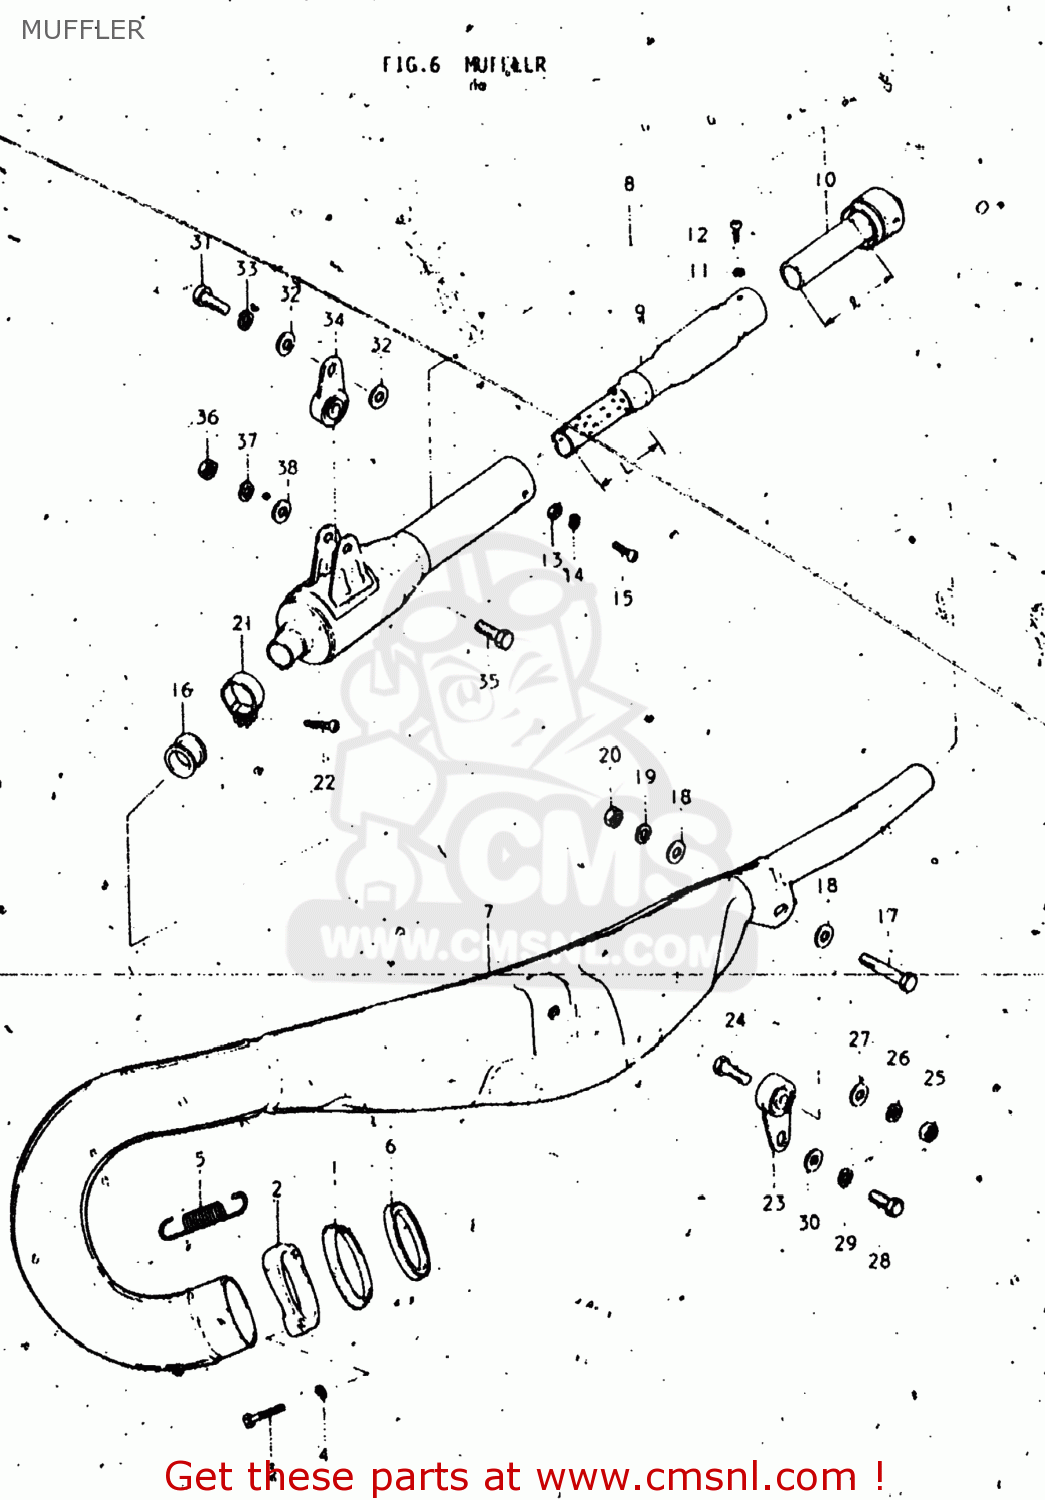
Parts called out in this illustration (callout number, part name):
1	GASKET,EXHAUST PIPE (NAS)
2	CLAMP,EXHAUST PIPE
3	BOLT
4	LOCK WASHER
5	SPRING
6	GASKET,EXHAUST PIPE
7	BODY,MUFFLER
8	MUFFLER ASSEMBLY
9	ARRESTER,SPARK
10	TUBE,MUFFLER CLEAN OUT
11	LOCK WASHER
12	SCREW
13	WASHER
14	LOCK WASHER
15	SCREW(6X8)
16	CONNECTOR,MUFFLER
17	BOLT 8X55
18	WASHER
19	LOCK WASHER
20	NUT
21	CLAMP
22	SCREW
23	DAMPER,MUFFLER SUPPORT
24	BOLT
25	NUT
26	LOCK WASHER
27	WASHER
29	LOCK WASHER
30	WASHER
31	BOLT
32	WASHER
33	LOCK WASHER
34	DAMPER,MUFFLER SUPPORT
35	BOLT
36	NUT
37	LOCK WASHER
38	WASHER
